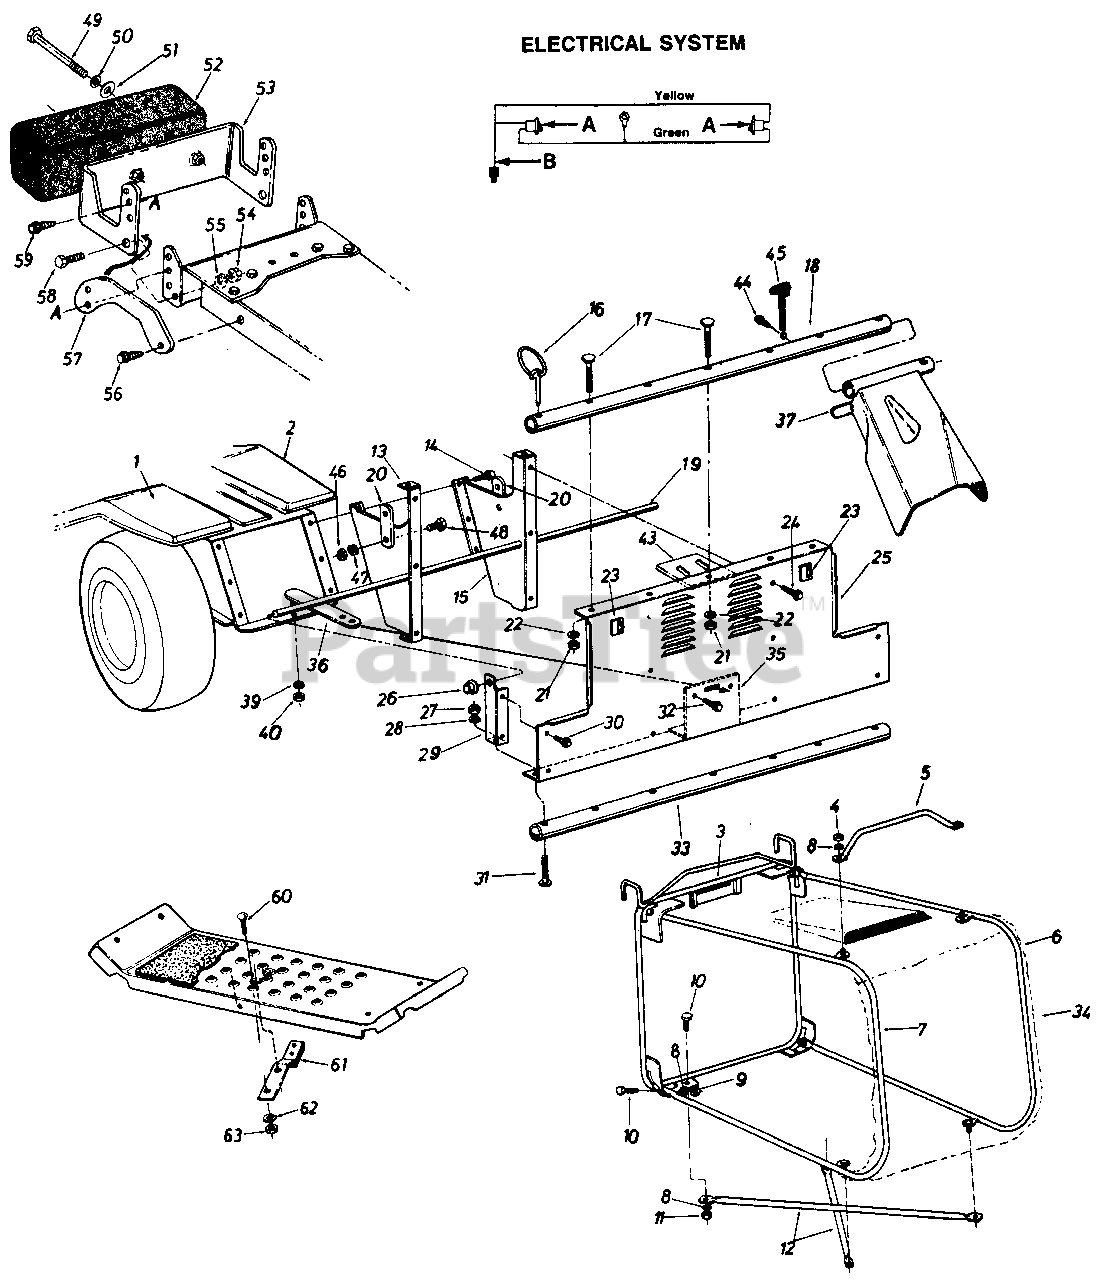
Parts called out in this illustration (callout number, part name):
3	Grass Catcher Frame Ass'y.
4	Hex Cent. L-Nut 1/4-20 Thd.
5	Grass Catcher Handle
9	Hex Cent. L-Nut 1/4-20 Thd.
10	Hex Bolt 1/4-20 x .62" Lg.
11	Hex Cent. L-Nut 1/4-20 Thd.
12	Bottom Cross Brace
13	Grass Catcher Support Brkt. L.H.
14	Hex Wash. Hd. Self-Tap Scr. 5/16-18 x .75" Lg.
15	Grass Catcher Support Brkt. R.H.
16	Klick Pin
17	Curved Carr. Bolt 5/16-18 x 1.75" Lg.
18	Grass Catcher Support Tube
19	Tubing .38" I.D. x 39.75" Lg.
20	Fender Support Brkt.
21	Hex Nut 5/16-18 Thd.
22	L-Wash. 5/16" I.D.
23	Safety Switch
24	Hex Wash. Hd. Self-Tap Scr. 1/4-20 x .50" Lg.
25	Grass Catcher Adapter
26	Cap Speed Nut 1/2" Rod
27	Hex Nut 5/16-18 Thd.
28	L-Wash. 5/16" I.D.
29	Chute Extension Support Brkt. L.H.
30	Hex Wash. Hd. Self-Tap Scr. 1/4-20 x .50" Lg.
31	Curved Carr. Bolt 5/16-18 x 1.75" Lg.
32	Hex Wash. Hd. Self-Tap Scr. 1/4-20 x .50" Lg.
33	Tubing 1.00" I.D. x 40.25"
34	Grass Catcher Bag
35	Hitch Bracket
40	Hex Jam Nut 1/2-13 Thd.
43	Grass Catcher Support Plate
44	Hex AB-Tap Scr. 1/4-20 x .62" Lg.
45	Spring Latch Ass'y.
46	Hex Nut 1/4-20 Thd.
47	L-Wash. 1/4" I.D.
48	Hex Bolt 1/4-20 x .50" Lg.
49	Hex Bolt 3/8-16 x 4.50" Lg.
50	Bell-Wash. .400" I.D. x .88" O.D.
51	Fl-Wash. 390" I.D. x 1.12" O.D.
52	Front Counterweight
53	Weight Bracket Ass'y.
54	Hex Jam Nut 7/16" Thd.
55	L-Wash. 7/16" I.D.
56	Hex Wash. AB-Tap Scr. 5/16 x 1.0" Lg.
57	Weight Brkt. Tie Strap
58	Hex Bolt 7/16-20 x 1.0" Lg.
59	Hex Wash. AB-Tap Scr. 5/16 x 1.0" Lg.
60	Carr. Bolt 1/4-20 x .62" Lg.
61	Blade Brake Ass'y.
62	L-Wash. 1/4" I.D.
63	Hex Nut 1/4-20 Thd.
